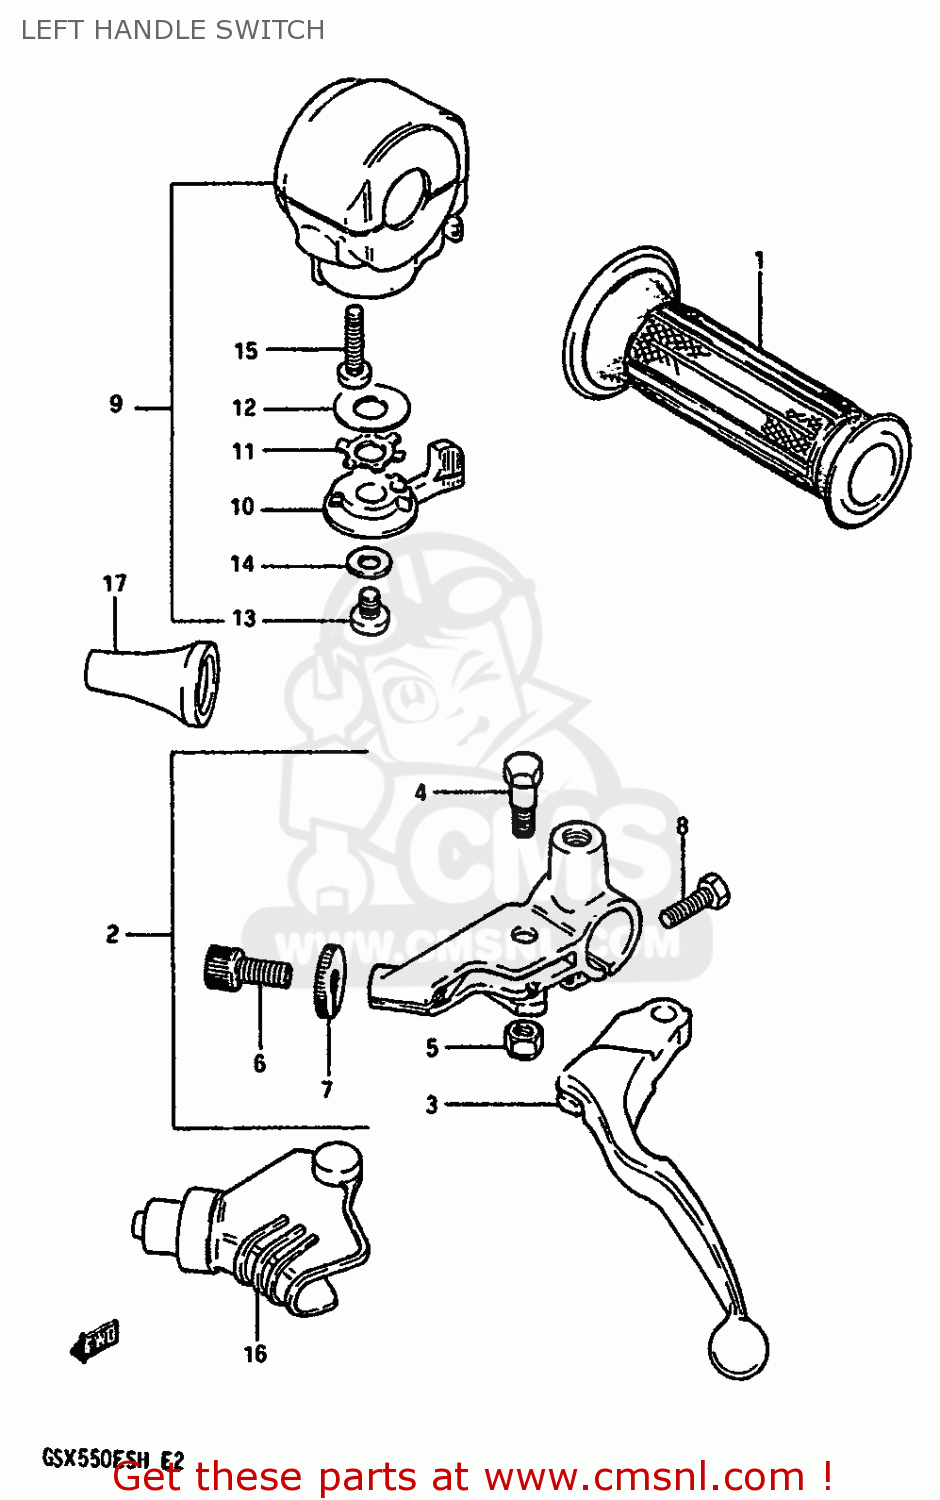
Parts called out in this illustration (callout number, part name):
1	GRIP,L
2	LEVER ASSY,CLU
3	LEVER,CLUTCH
4	BOLT,LEVER
5	NUT
6	ADJUSTER,CABLE
7	NUT,CABLE ADJUSTER
8	BOLT
9	SWITCH ASSY,HA
10	LEVER,STARTER
11	WASHER
12	WASHER
13	SCREW
14	WASHER
15	SCREW
16	COVER,CLUTCH LEVER
17	BOOT,CLUTCH CABLE
